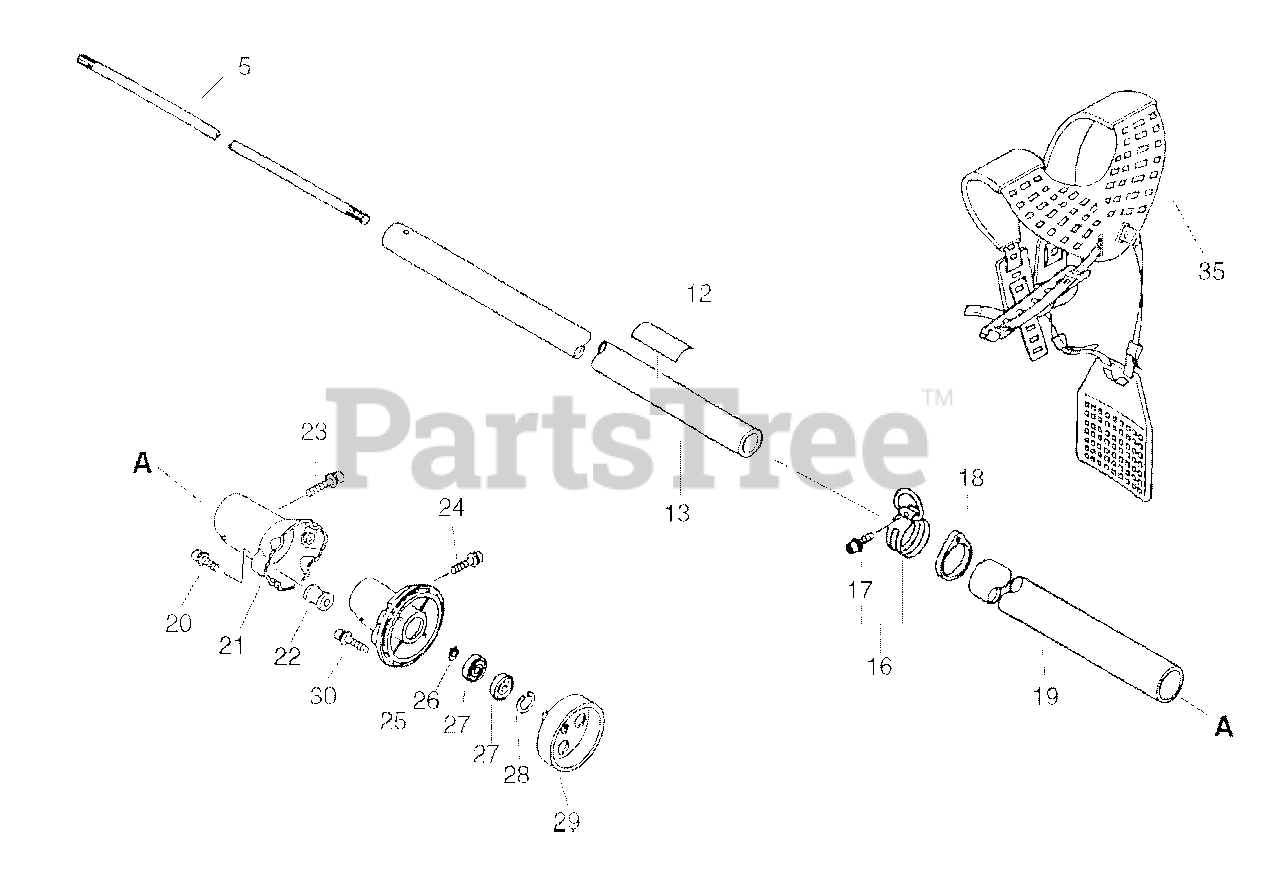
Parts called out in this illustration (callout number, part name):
5	DRIVESHAFT
12	LABEL, CAUTION - ISO
13	MAIN PIPE ASSY
13	PIPE, MAIN
16	HANGER KIT
17	BOLT 5×20
18	CLAMP
19	PIPE, MAIN
20	BOLT 5×14
21	COVER
23	BOLT M5×35
24	BOLT 5×30
25	CASE, CLUTCH
26	RING, RETAINING 15
27	BEARING, BALL 6203
28	RING, SNAP 35
29	DRUM, CLUTCH
30	BOLT 5×20
35	HARNESS, SHOULDER
